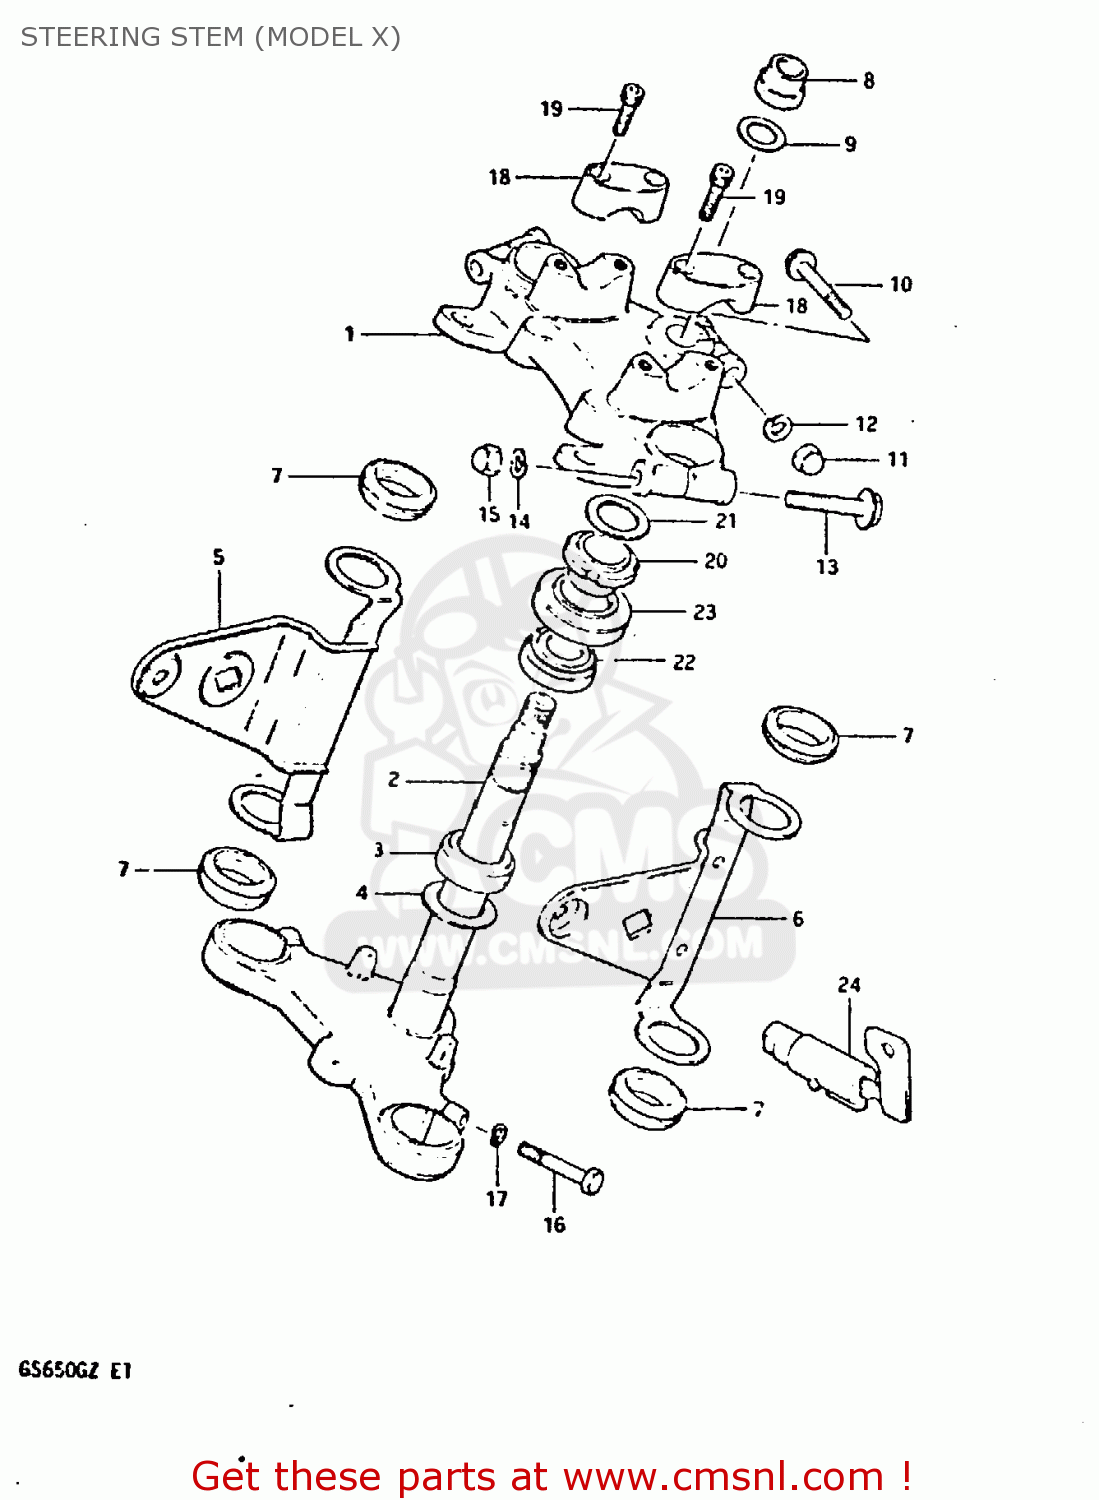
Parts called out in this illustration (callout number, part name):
1	STEM HEAD, STEERING (BLACK)
2	STEM, STEERING
3	BEARING
4	WASHER,THRUST
5	BRACKET,HEADLAMP,RIGHT
6	BRACKET,HEADLAMP,LEFT
7	CUSHION,HEADLAMP BRACKET
8	NUT,STEERING STEM
9	WASHER,STEM HEAD
10	BOLT
11	NUT,M8X1.25X12
12	LOCK WASHER
13	BOLT 10X55
14	LOCK WASHER
15	NUT
16	BOLT 10X40
17	LOCK WASHER
18	HOLDER,HANDLEBAR(BLACK)
19	BOLT
20	NUT,STEERING STEM
21	WASHER(18.5X24X1)
22	TAPER,ROLLER BEARING
23	DUST SEAL,STEERING,UPPER
